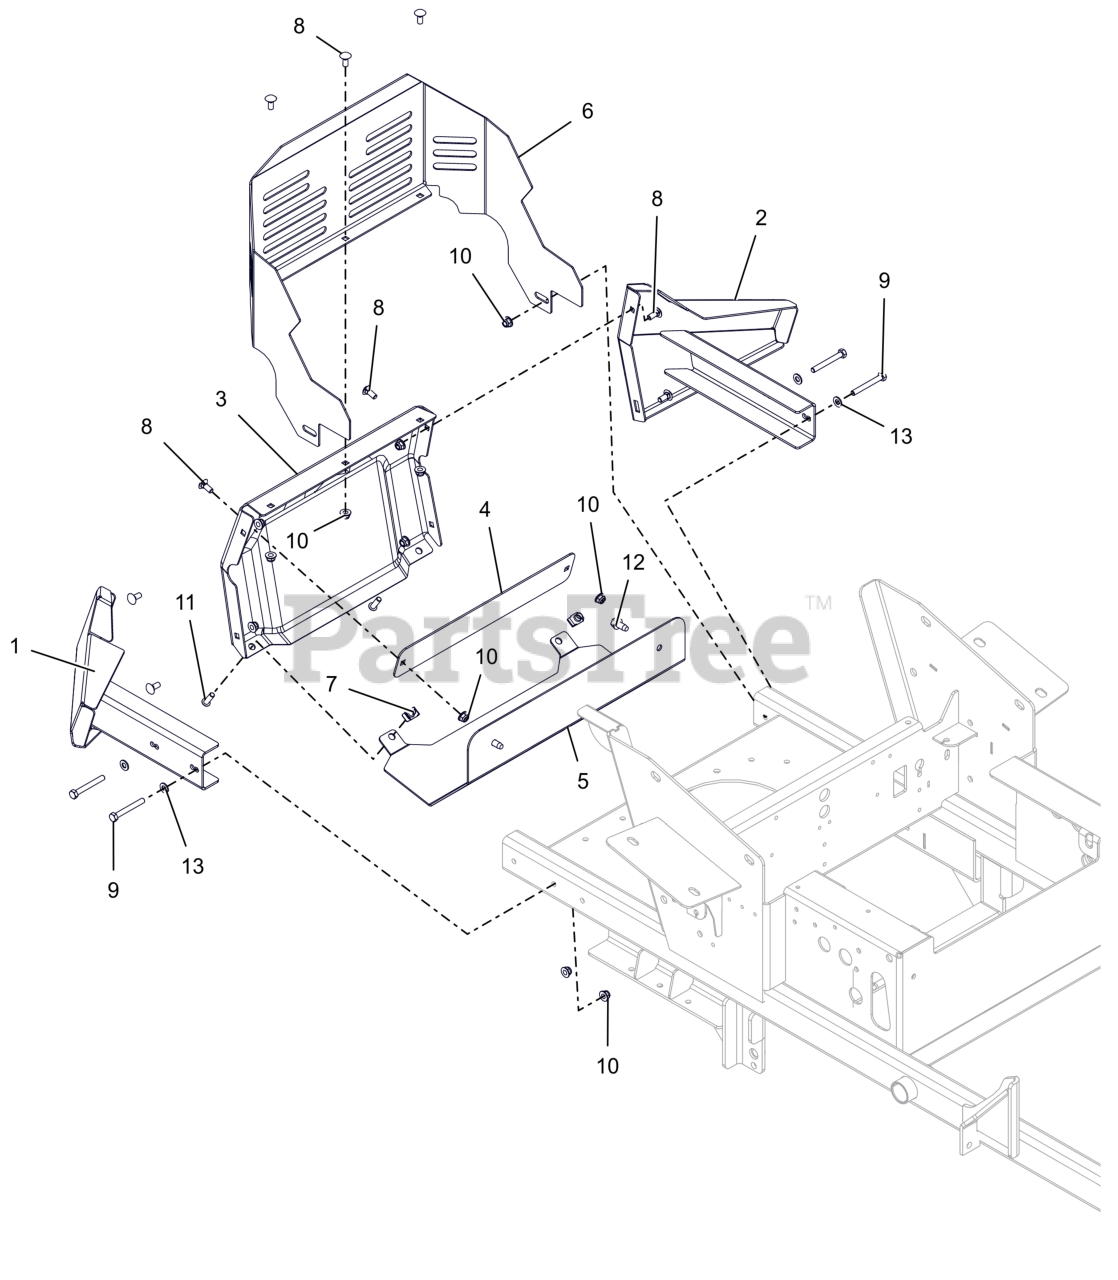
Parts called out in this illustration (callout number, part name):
1	RH RR BMPR WING W/SAFETY DECAL
2	LH RR BMPR WING W/SAFETY DECAL
3	PT200/400 REAR BUMPER - BLACK
4	BACKER PLATE - RED
5	PT100 MUFFLER GUARD -BLACK
6	GUARD, PT100 ENGINE
7	NUT-CLIP RETAINER 5/16-18X.56
8	BLT,RHSN .31-18X.75 G5 ZCC
9	BLT, HEX 0.3125-18X2.5 GR5 ZCC
10	NUT,NYL-FLG .31-18 GF ZCC
11	BLT,SHCS-BTN .31-18X1.00 ZCC
12	SCR,TAP .375-16X.75 HWH TR ZCC
13	WSHR,FLT .344X.688X.065 ZCC
